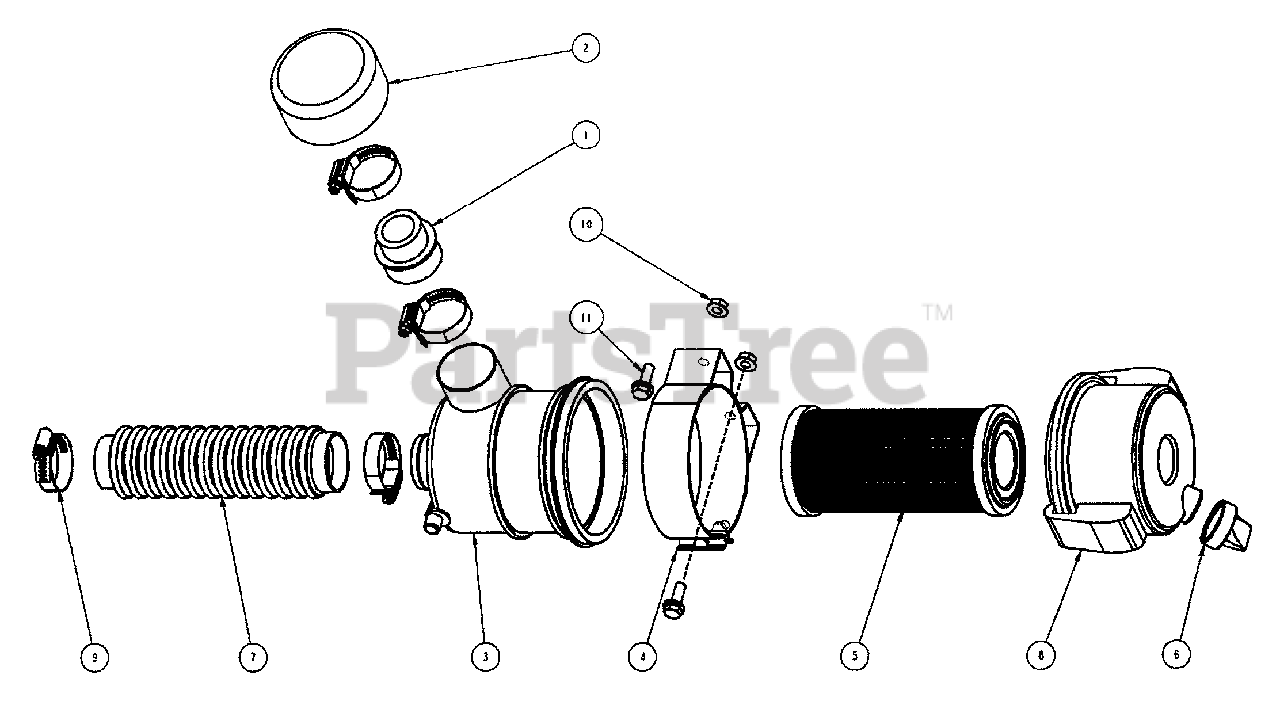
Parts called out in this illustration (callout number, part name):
1	RESTRICTER, AIR CLEANER
2	PRECLEANER
3	FILTER HOUSING
4	MOUNTING BRKT
5	FILTER ELEMENT
6	DRAIN VALVE
7	FLEX TUBE, 1.5 X 1.75 X 8
8	CAP, AIR FILTER
9	CLAMP, HOSE
10	FLN, 5/16-18 YZ
11	HFLB, 5/16-18 x 7/8-YZ
